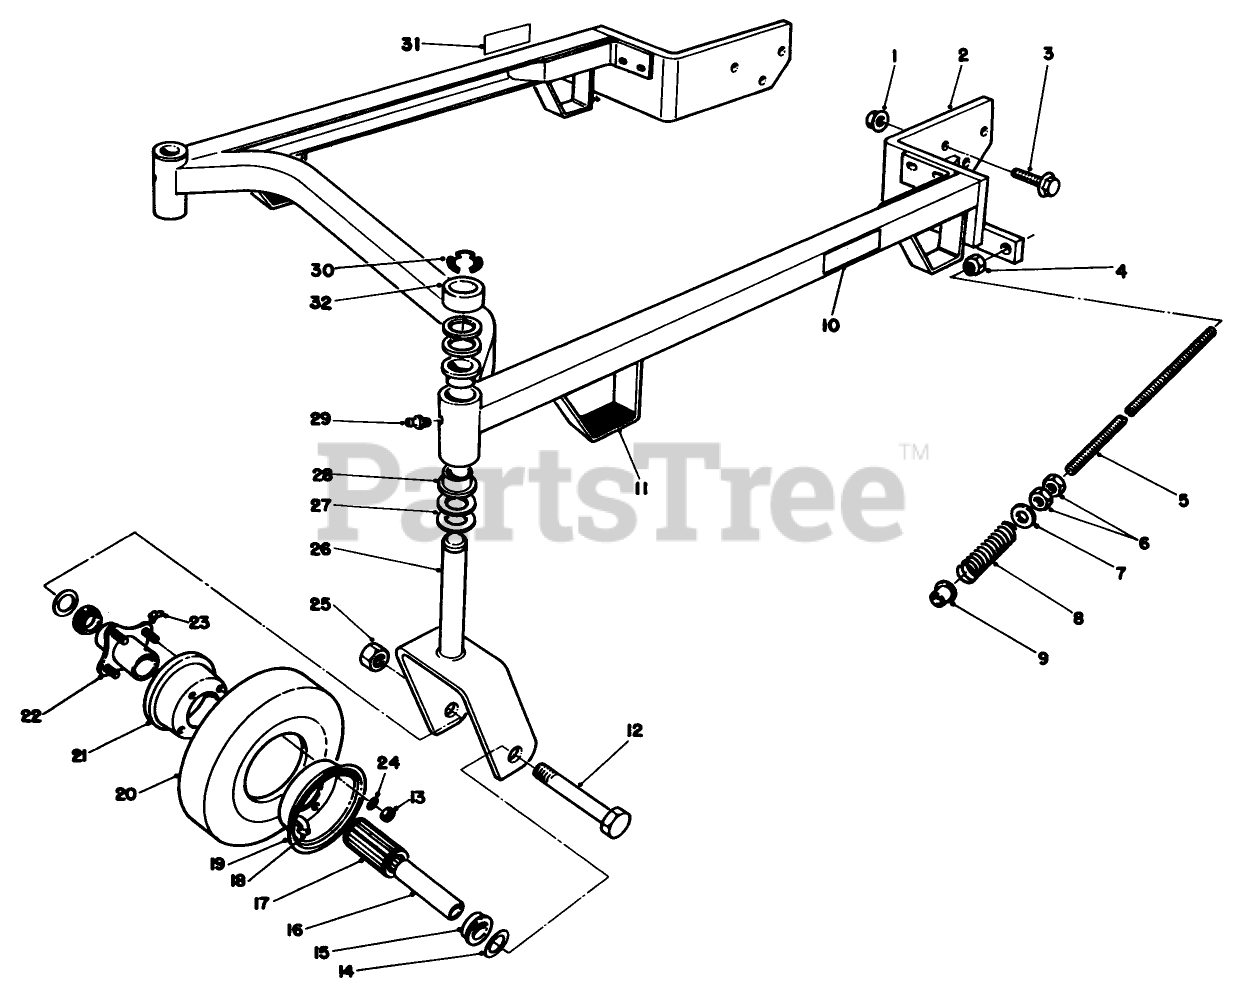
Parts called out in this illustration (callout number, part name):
1	NUT-HF
2	Frame-Suspension (Incl. Ref. #28)
3	SCREW-HHF
4	NUT-LOCK, NI
5	SHAFT-ADJUSTING
6	NUT-JAM
7	WASHER
8	SPRING
9	BUSHING-FLANGE
10	DECAL-HOC, LH
11	CUSHION-RUBBER
12	SCREW-HH
13	NUT-HEX
14	WASHER-FLAT
15	BEARING-OUTSIDE
16	SPANNER-TIRE
17	BEARING-ROLLER
18	TUBE-INNER (W/VALVE)
19	FEMALE WHEEL HALF
21	MALE WHEEL HALF
22	HUB-CENTER
23	FITTING-GREASE
24	WASHER-FLAT
25	NUT-HEX
26	Fork
27	WASHER-THRUST
28	Bushing
29	FITTING-GREASE
30	RING-RETAINING
31	DECAL-HOC, RH
32	SPACER-CASTOR
